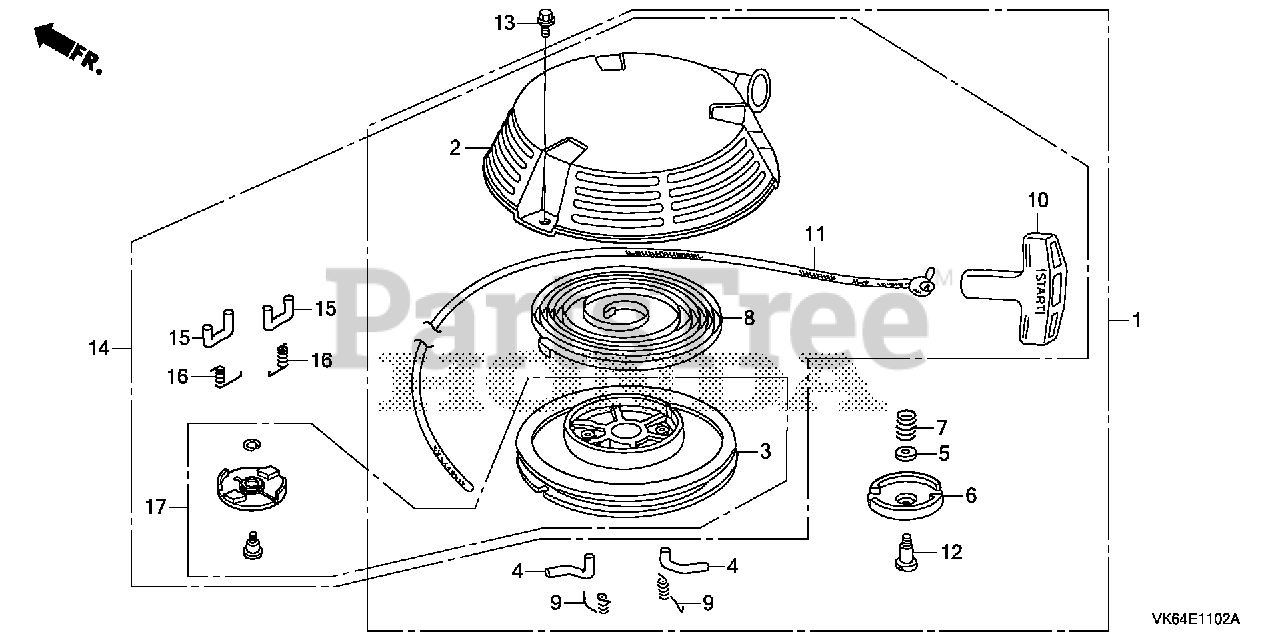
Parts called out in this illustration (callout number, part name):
1	STARTER ASSY., RECOIL *R280* (LONG ROPE) (POWER RED)
2	CASE, RECOIL STARTER *R280* (POWER RED)
3	REEL, RECOIL STARTER (BLACK)
4	RATCHET, STARTER
5	PLATE, FRICTION
6	GUIDE, RATCHET
7	SPRING, FRICTION
8	SPRING, RECOIL STARTER
9	SPRING, RETURN
10	KNOB, RECOIL STARTER
11	ROPE, RECOIL STARTER (2360MM) (LONG)
11	ROPE, RECOIL STARTER (LONG TYPE)
12	SCREW, SETTING
13	BOLT, FLANGE (6X8)
14	STARTER ASSY., RECOIL *R280* (LONG ROPE) (POWER RED)
15	RATCHET, STARTER
16	SPRING, RETURN
17	STARTER SET, RECOIL
